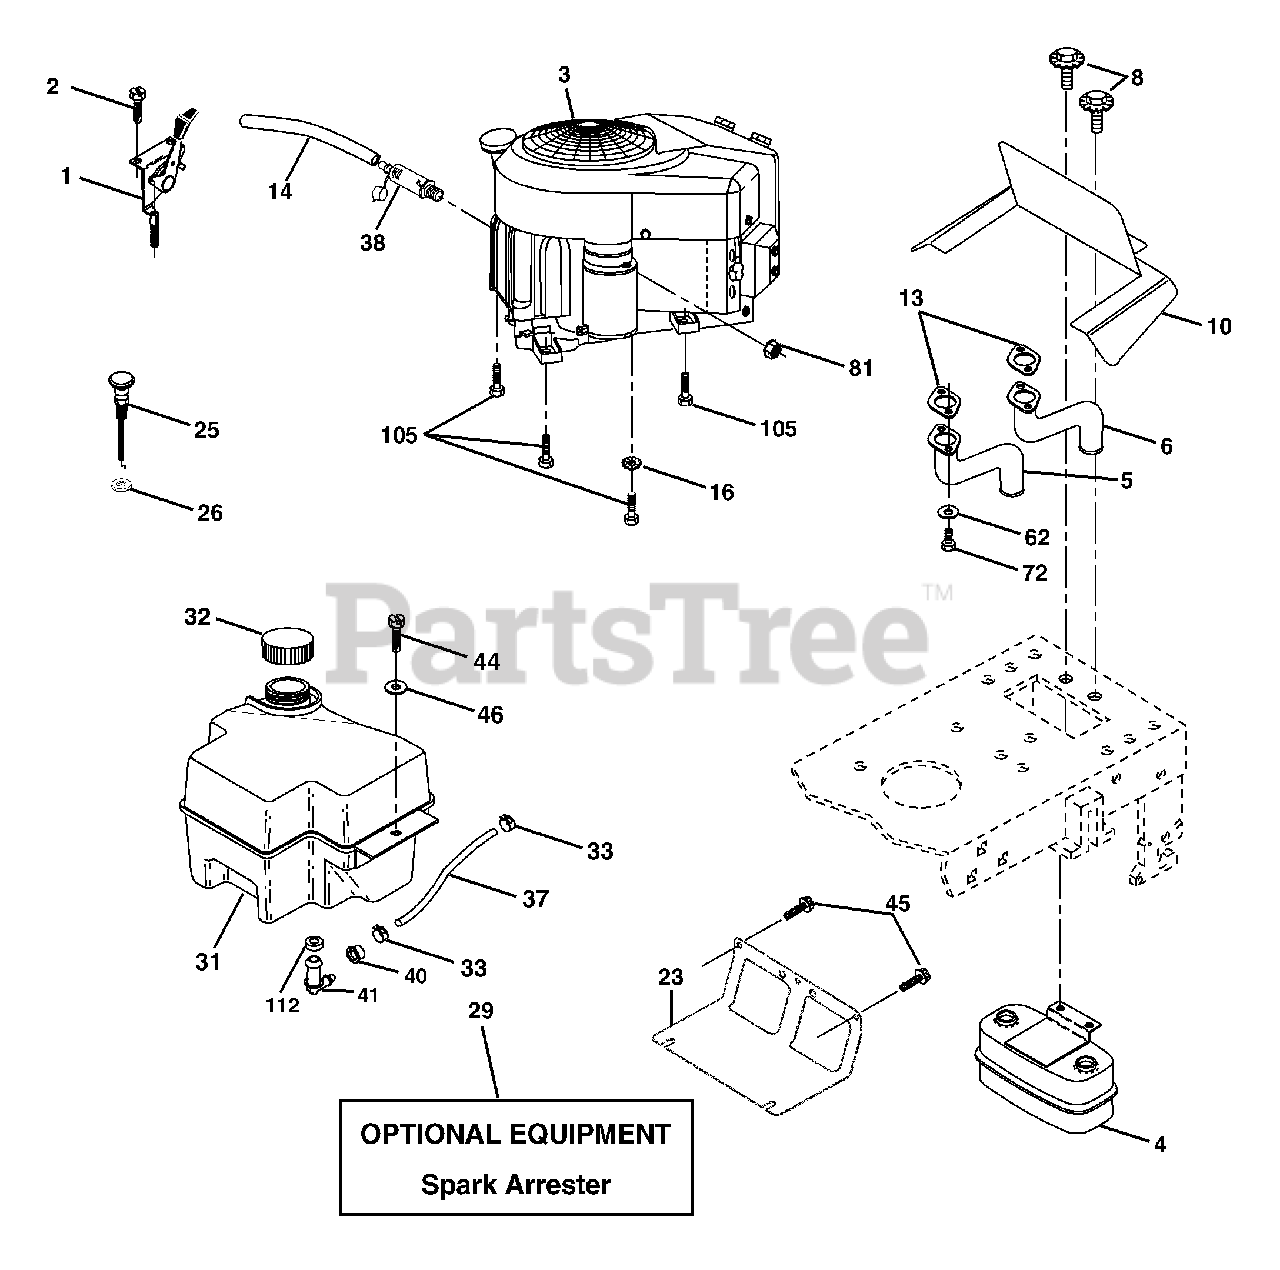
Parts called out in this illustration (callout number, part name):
1	Control Throt /Ch Flag
2	Screw Hex Thd Cut 1/4-20x1/2
4	Muffler
5	Exhaust Tube LH
6	Exhaust Tube RH
8	Bolt 5/16-18unc x 3/4
10	Shield Muffler
13	Gasket
14	Tube Drain Oil Easy
16	Washer Lock Ext Tooth 3/8
23	Shield Browning/Debris Guard
25	Control Choke
26	Nut Keps 3/8-24 Unf
29	Arrestor Spark
31	Tank Fuel
32	Cap Asm Fuel W/sym Vented
33	Clamp Hose Blk
37	Line Fuel 20"
38	Plug Drain Oil Easy
40	Bushing Snap
41	Stem Fuel Tank
44	Screw Hexwsh Thdrol 1/4-20x3/4
45	Screw Hex Wsh Thdrol 3/8-16
46	Washer 9/32 X 7/8 X 16ga
62	Washer Lock 5/16
72	Screw Hex Hd Cap 5/16-18 x 3/4
81	Nut Keps Hex 1/4-20 Unc
105	Screw Thdrol 3/8-16x1-1
112	Bushing, Outlet
